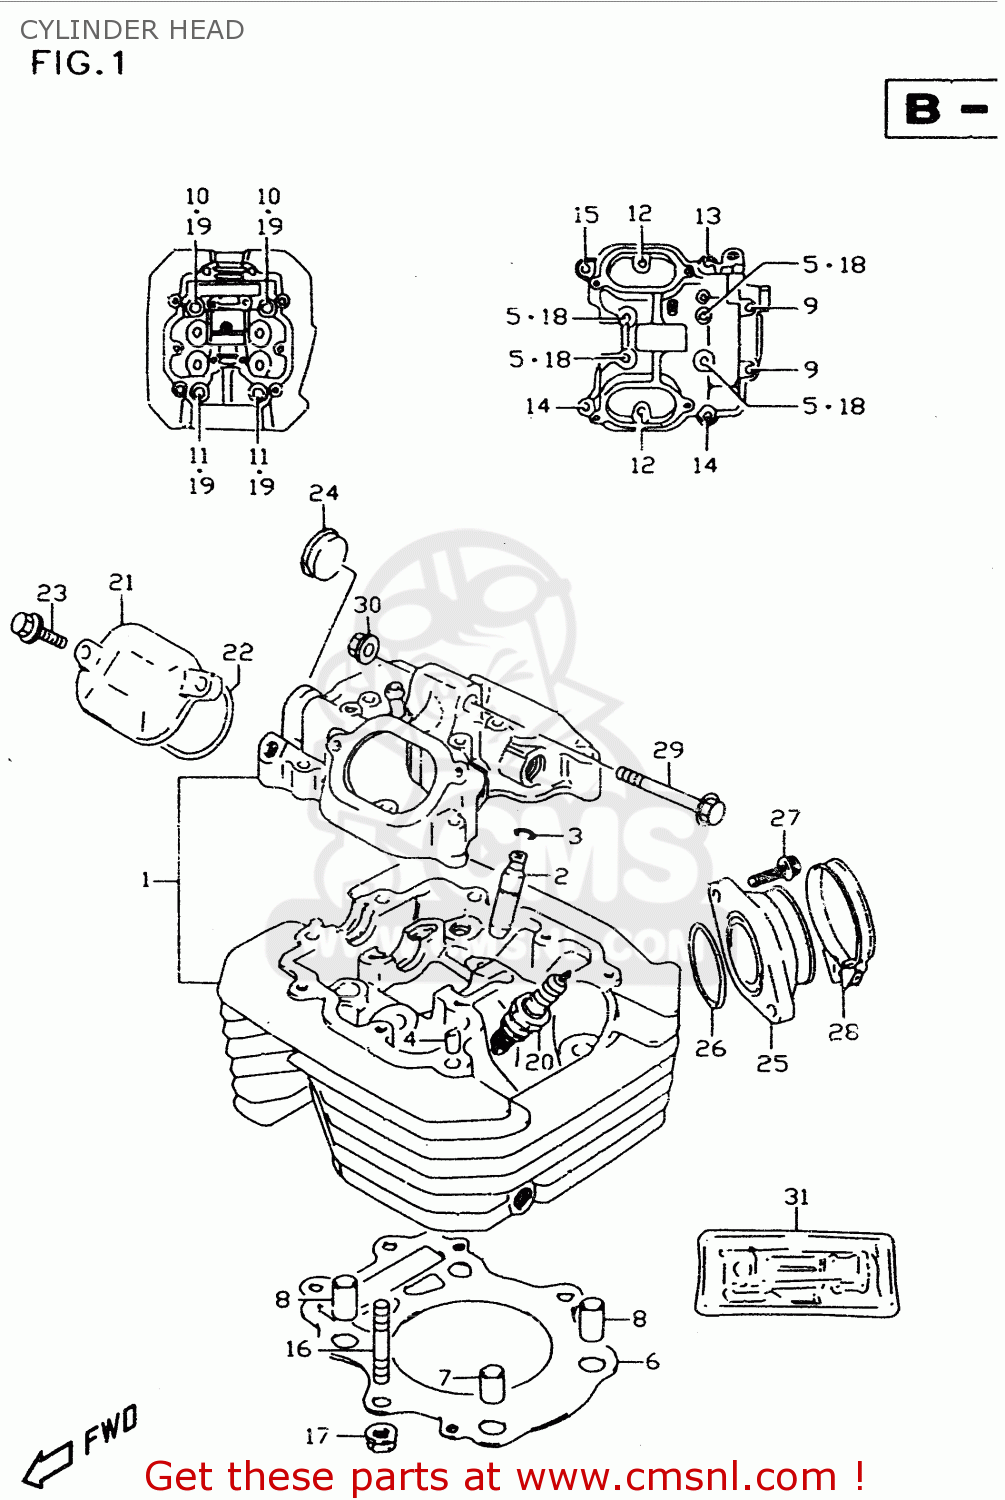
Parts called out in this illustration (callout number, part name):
1	HEAD ASSY,CYLINDER
2	GUIDE,VALVE
3	RING,SNAP
4	PIN(6.2X8X11)
5	BOLT(6X55)
6	GASKET,CYLINDER HEAD (NAS)
7	PIN
8	PIN(10.4X13X22)
9	BOLT(6X115)
10	BOLT(10X180)
11	BOLT(10X155)
12	BOLT
13	BOLT
14	BOLT(6X35)
15	BOLT(6X39)
16	BOLT,STUD
17	NUT
18	GASKET(5.8X13X1.2) (NAS)
19	WASHER (10.5X22X2.3)
20	PLUG,SPARK(CR9EK)
21	CAP,INSPECTION
22	GASKET (NAS)
23	BOLT
24	PLUG,OD:30
25	PIPE ASSY,INTAKE
26	O RING(D:2.4,ID:39.7)
27	BOLT
28	CLAMP
29	BOLT(8X65)
30	NUT
31	GASKET SET (NAS)
